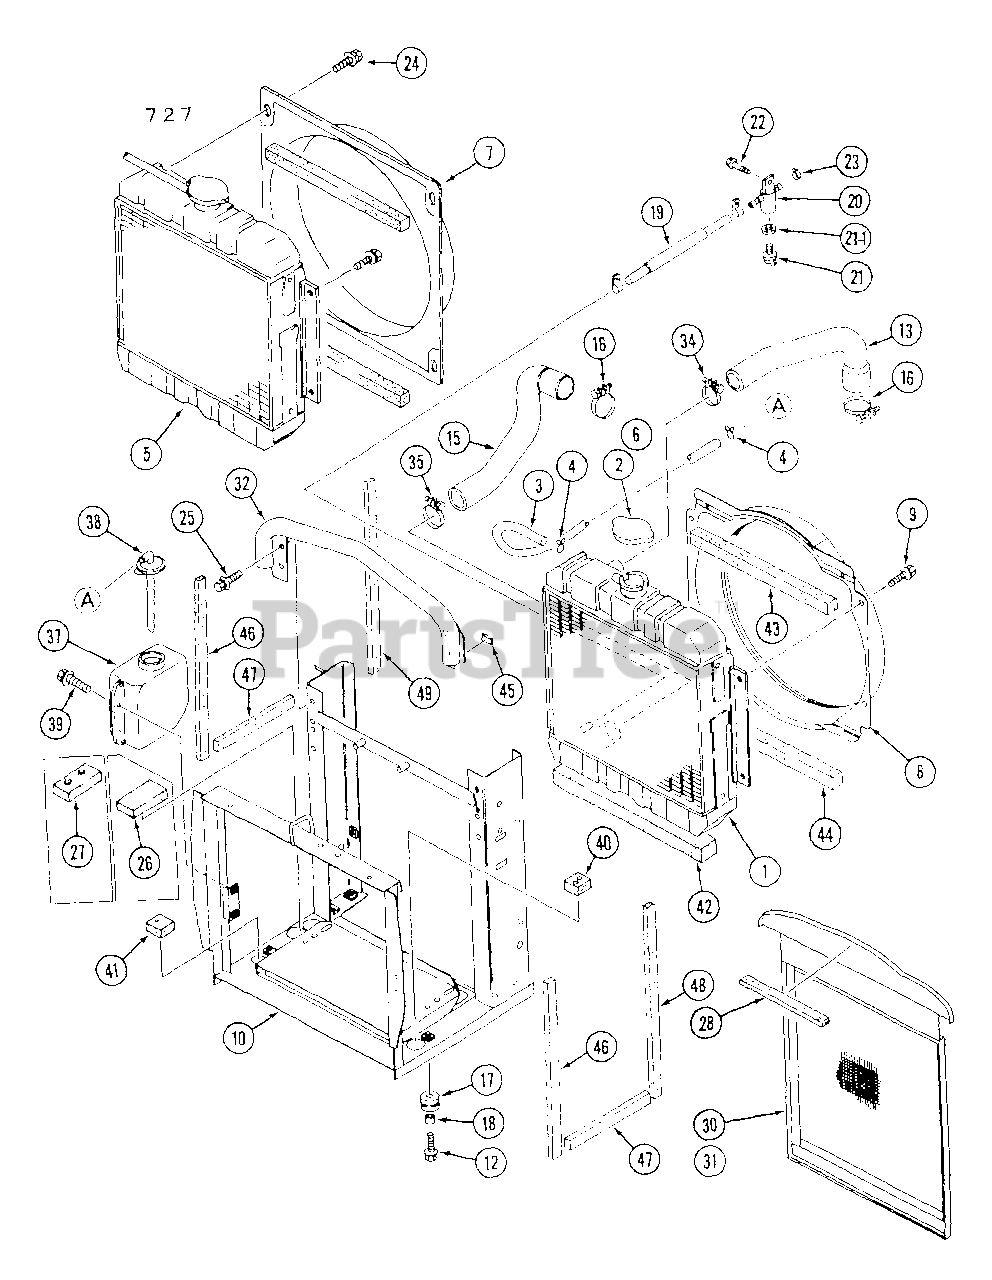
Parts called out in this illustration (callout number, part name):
1	Body, Radiator
5	Body, Radiator
6	Cap
7	Shroud, Fan
10	Bracket, Radiator
16	Clip, Hose
19	Hose, Drain
21	Water Cock Ass'y.
23	Clamp Hose
24	Bolt
26	Cushion
30	Net, Radiator
31	Net, Radiator
